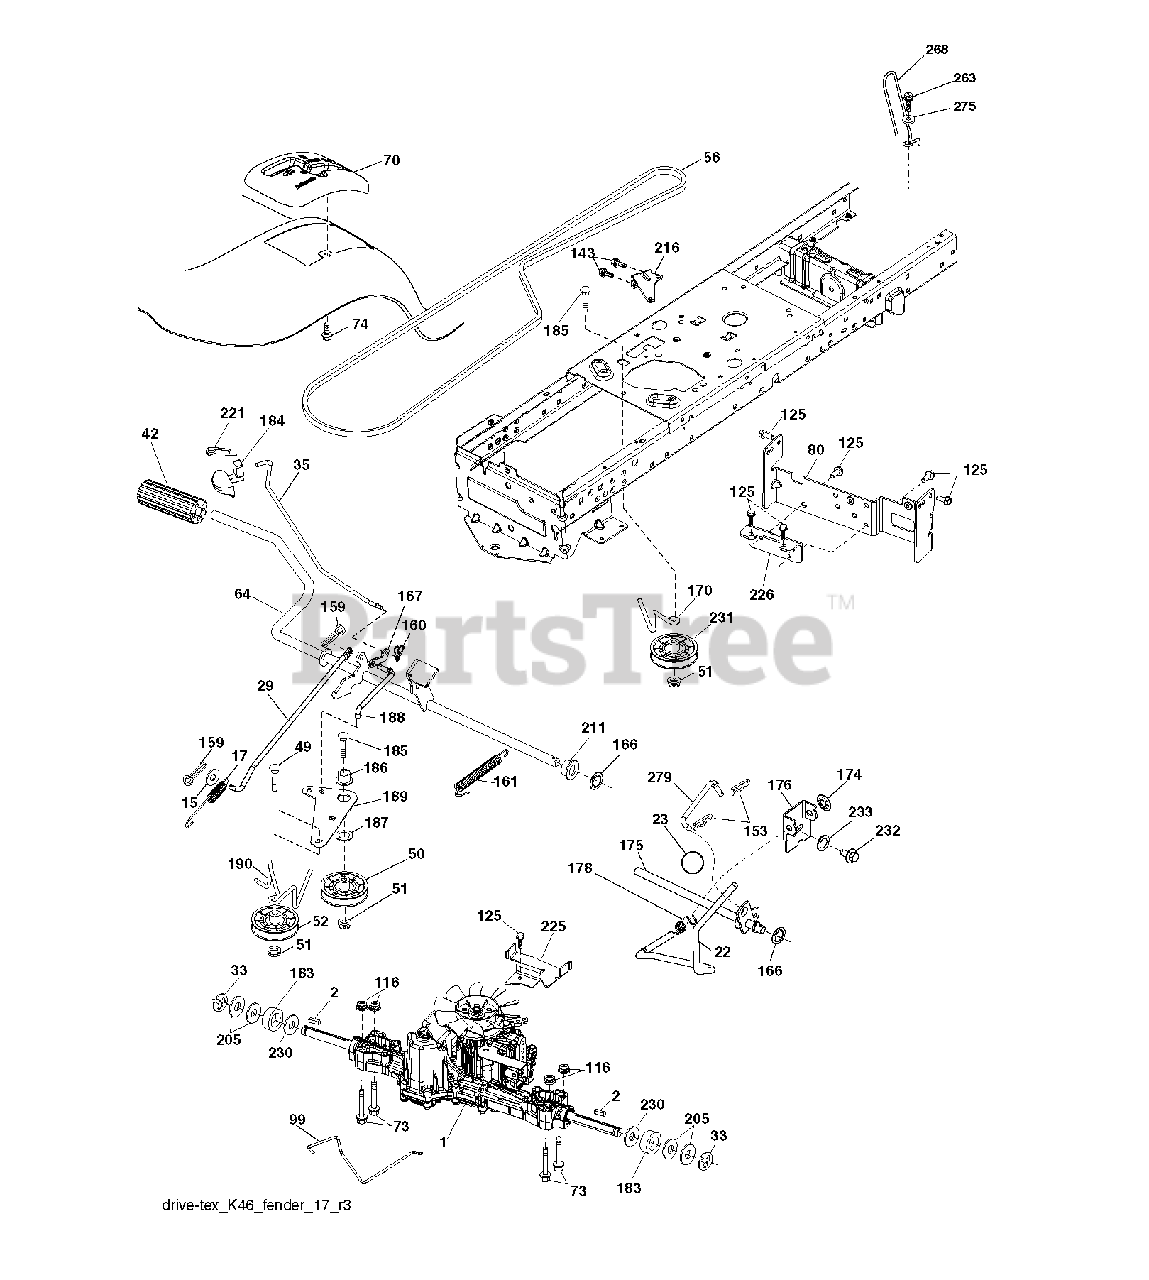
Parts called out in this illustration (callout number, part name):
2	SQUARE KEY
17	SPRING.BRAKE.K46.GREEN
22	ROD.SHIFT.FENDER.TLT.2006
23	KNOB.DUCKHEAD.1/2
29	ROD.BRAKE.K46
33	E-RING LT
35	ROD, BRAKE, PARK
42	PEDAL COVER T
49	BOLT
50	IDLER.FLAT.910.OFFSET
51	NUT LOCK FLG 3/8-16 UNC
52	IDLER.V-GROOVE.910.OFFSET
64	SHAFT.ASM.PEDAL.BRAKE.
70	CONSOLE.SHIFT.STL.HYD.BLACK
73	BOLT HEX 5/16-18 GR 5
74	SCREW.HI-LO.CONSOLE
80	STRAP TORQUE
99	ROD.SPRING.BYPASS.K46.LT.Z
116	NUT LOCK HEX FLANGE 5/16-18
125	SCREW
143	SCREW LT
153	RETAINER M
159	COTTER PIN
160	RETAINER CLIP
161	SPRING, RETURN LT
166	NUT.PUSH.625
167	LATCH.BRAKE.SPRING
170	KEEPER.CENTER SPAN.1.688
174	NUT.PUSH.500.2006
175	SHAFT.ASM.SHFT.T2.TLT
176	ARM.CLEVIS.ROD.SHIFT
178	SPRING.SHIFT.GT2006
183	SPACER AXLE
184	HANDLE PARKING BRAKE
186	SPACER.RETAINER
187	WASHER 12/32X2X10GA
188	LINK.CLUTCH.GROUND.DRIVE
189	BELLCRANK.GROUND.DRIVE.TEX.
190	KEEPER.BELLCRANK.DRIVE
211	BUSHING.SHAFT.BRAKE.HAND
216	BRACKET.PULLEY.IDLER.W/TEX
221	RETAINER.SPRING.CLIP.H
225	KEEPER.BELT.TRANSAXLE.K46
226	BRACKET.MOUNT.TORQUE.K46.TLT
230	WASHER.HARDENED
231	IDLER.V-GROOVE.1.688.OFFSET
232	BOLT FIN HEX 7/16-14 X 1
233	WASHER SERRATED
263	SCREW, 3/8-16X3/4
275	WASHER
279	LINK.SHIFT.T2
